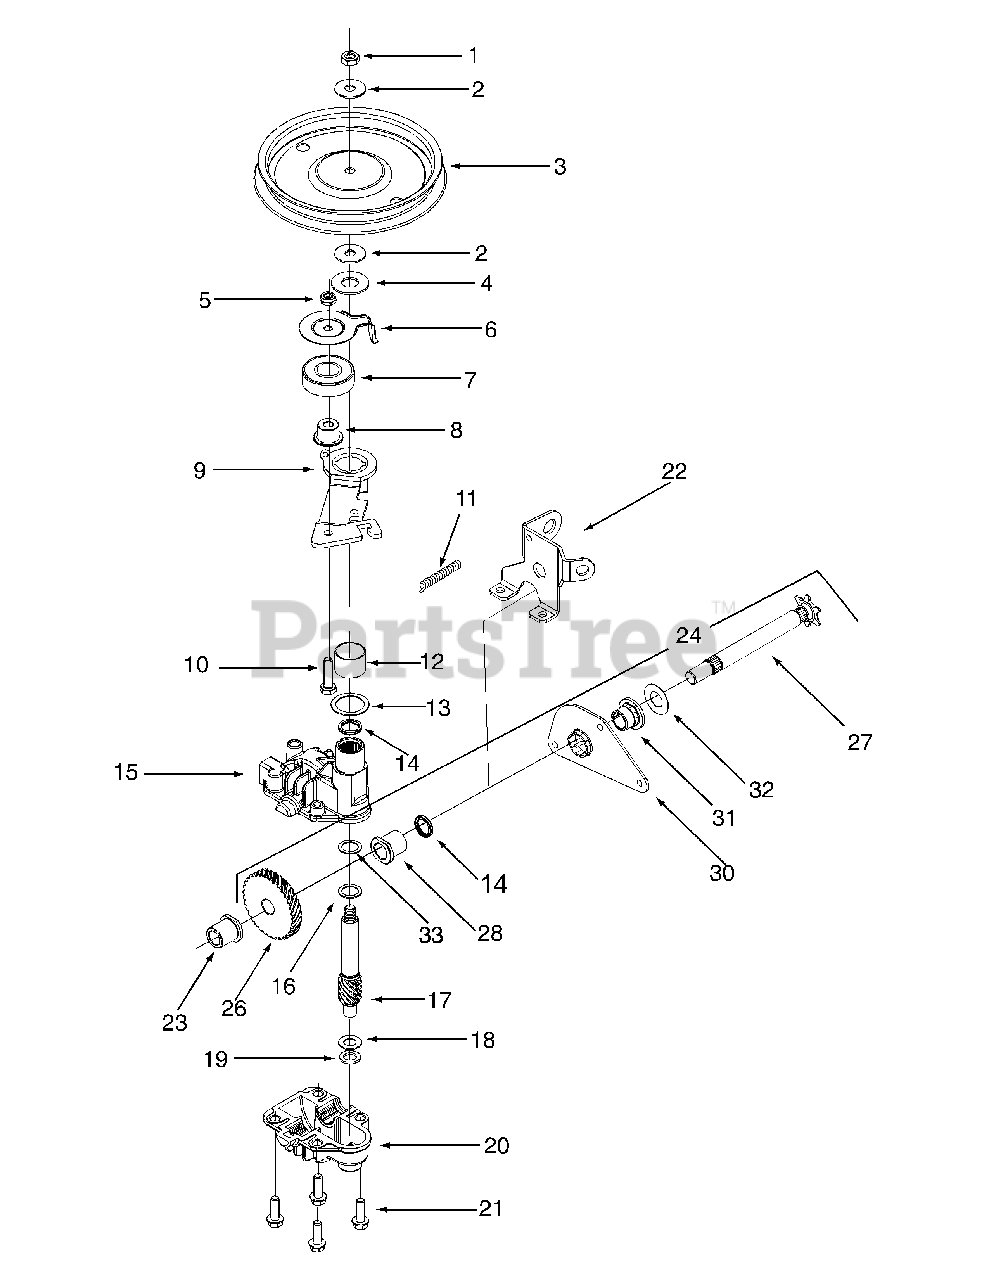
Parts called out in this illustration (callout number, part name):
1	Hx. Jam Nut 5/16-24
2	Bell Wash. .325 x .930 x .045
3	Pulley
4	Fl. Wash. .510 x 1.120 x .060
5	Hx. Jam Nut 1/4-28
6	Belt Keeper
7	Bearing
8	Flange Spacer
9	Idler Bracket Ass’y.
10	Hx. Cap Scr. 1/4-28 x 1.00 Gr. 5
11	Torsion Spring
12	Bearing Sleeve
13	Fl. Wash. .885 x 1.145 x.030
14	Oil Seal
15	Upper Housing Ass’y.
16	Fl. Wash. .504 x .700 x .030
17	Pinion Shaft 10 T.
18	Thr. Wash. 3/8 x .70 x .030
19	Thr. Wash. .388 x .625 x .062
20	Lower Housing Ass’y.
21	Hx. Scr. 1/2-20 x .75
24	Shaft Ass’y.
26	Gear 34 T.
27	Output Shaft 6 T.
28	Flange Bearing
30	Pivot Bracket
31	Flange Bearing
32	Wash. Fl. .508 I.D. x 1.00 O.D. x .020
33	Thrust Bearing
